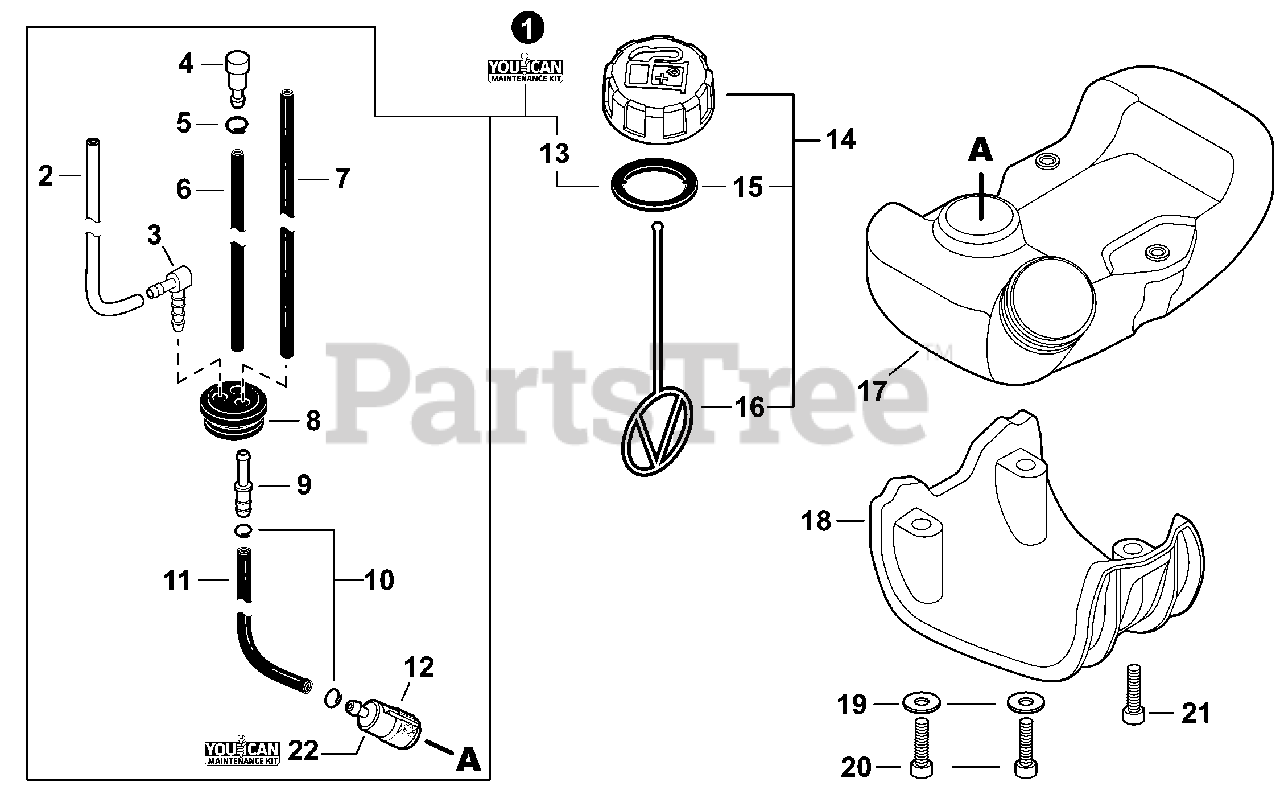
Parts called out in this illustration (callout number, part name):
1	FUEL SYSTEM KIT - YOUCAN™
2	PIPE, FUEL 3×6×80 CLEAR
3	CONNECTOR, PIPE
4	VENT ASSY
5	CLIP Ø6.5MM
6	PIPE, FUEL 3×6×85
7	PIPE, FUEL 3×5×83 BLACK
8	GROMMET, FUEL
9	CONNECTOR, PIPE Ø5ר3.5
10	CLIP Ø6
11	PIPE, FUEL - 3×5×125 - BLACK
12	FILTER, FUEL
13	GASKET, FUEL CAP
14	CAP ASSY, FUEL
15	GASKET, FUEL CAP
16	CONNECTOR, CAP L= 123
17	TANK, FUEL
18	GUARD, FUEL TANK
19	WASHER 5.3×10×1
20	BOLT, TORX 5×25
21	BOLT, TORX 5×20
22	TUNE-UP KIT - YOUCAN™
